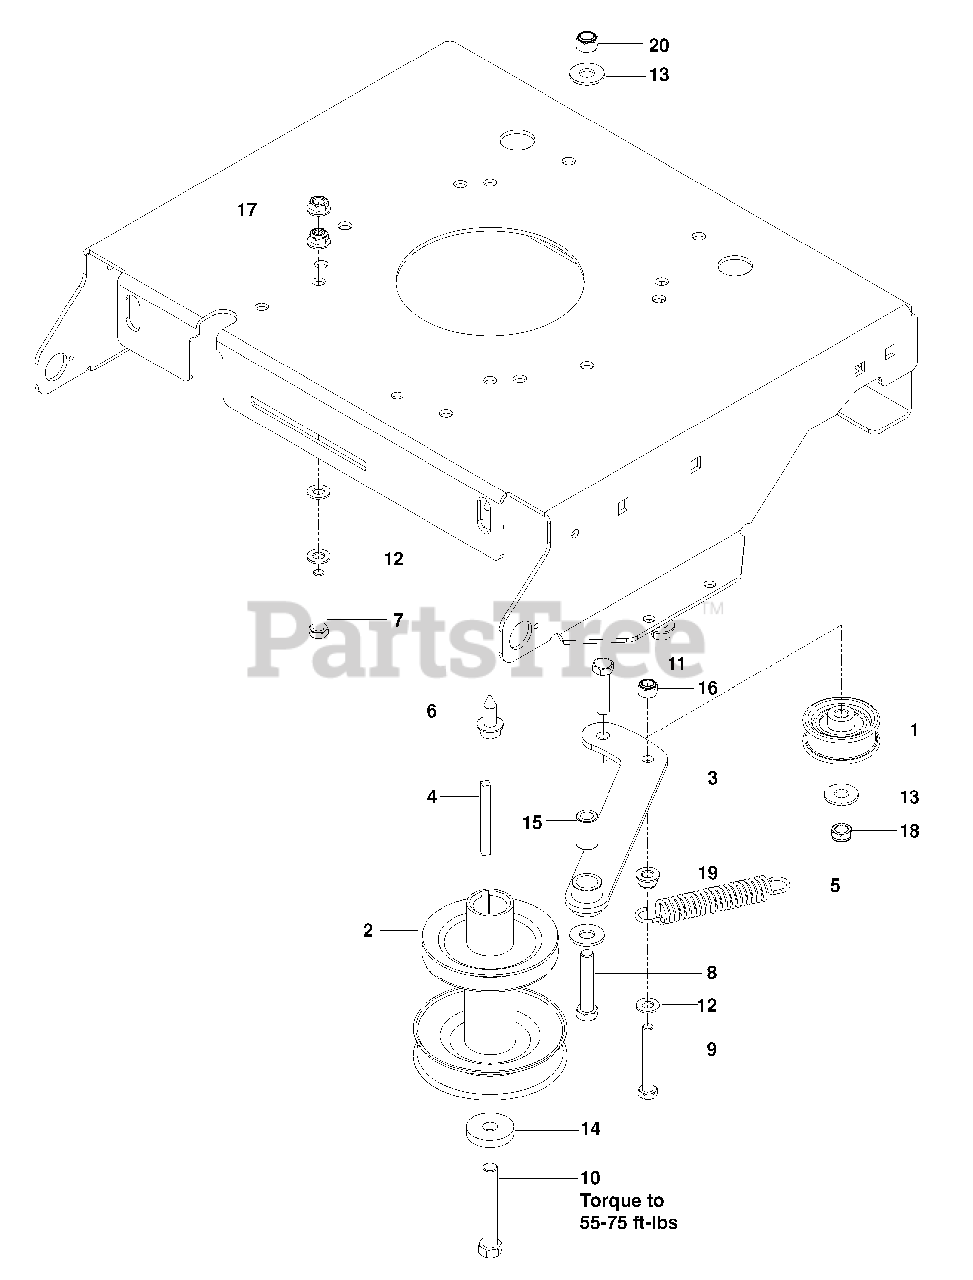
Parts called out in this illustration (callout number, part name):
1	PULLEY, IDLER
2	PULLEY, ENGINE
3	IDLER, BLK
4	KEY 1/4 SQ x 2 1/2 LG
5	SPRING 3 1/2
6	SCREW 3/8-16 x 1 THD FRM
7	HCS 5/16-18 x 2
8	HCS 3/8-16 x 2
9	HCS 5/16-18 x 2 1/4
10	HCS 7/16-20 x 2 3/4
11	HCS 3/8-16 x 1 1/2
12	WASHER 5/16 SAE FLAT
13	WASHER 3/8 FLAT STD
15	BUSHING, METAL
16	NUT 5/16-18 HEX NYLOC
17	NUT 5/16-18 HEX WHIZLK
18	NUT 3/8-16 HEX JAM NYLOC
19	NUT 5/16-18 FLANGE NYLOC
20	NUT 3/8-16 HEX NYLOC
